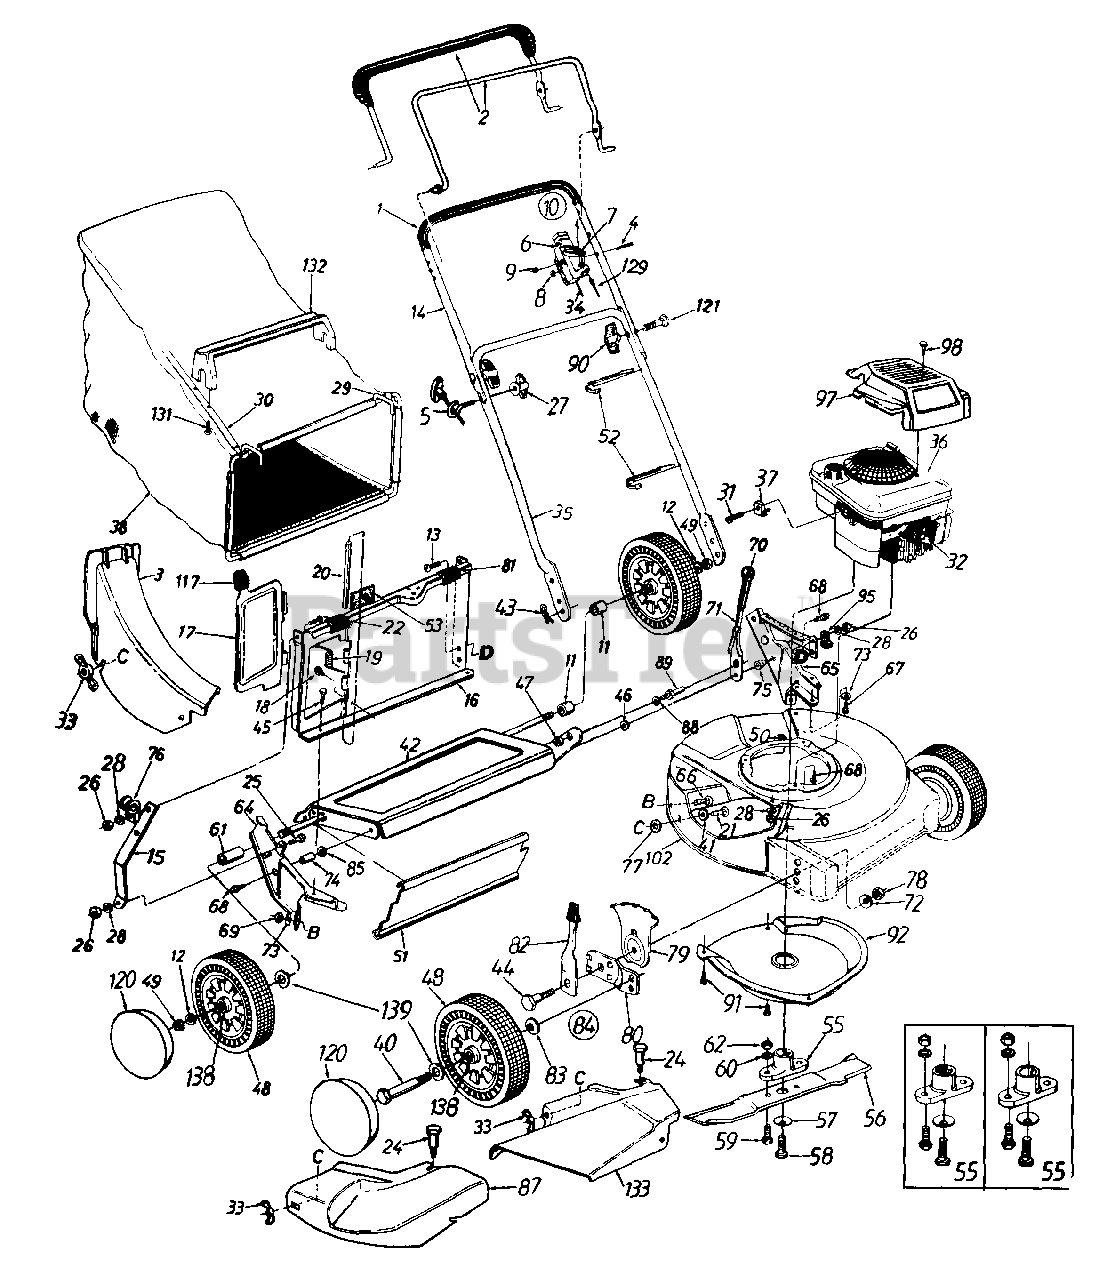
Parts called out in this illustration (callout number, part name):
1	Grip
3	Top Discharge Chute Ass'y.
4	Oval C-Sunk Ser.
5	Rope Guide
6	Throttle Body
7	Throttle Lever
8	Spr. Wash .66" I.D.
9	Hex L-Nut 1/4-20 Thd.
10	Throttle Box Comp.
11	Spacer .526" I D. x .690" O.D. x .640" Lg.
12	Fl-Wash .510" I.D. x .75"
13	Truss Mach. Scr. 1/4-20 x .62"
14	Upper Handle
19	Torsion Spring
20	Pivot Pin
21	Carriage Bolt 1/4-20 x .62"
22	Truss Mach. Scr. 1/4-20 x .75"
24	Shoulder Bolt .312" Dia. x .18" Lg. Special
25	Hex Bolt 1/4-20 x .62" Lg.
26	Hex Nut 1/4-20 Thd.
27	Handle Knob 1/4-20 Thd.
28	L-Wash. 1/4" I.D.
31	Hex Self-Tap Scr. #10-32 x .62"
32	Spark Plug Insulator
33	Wing Nut w/Washer
34	Throttle Control Wire 61"
36	Engine
37	Cable Clamp
38	21" Top Discharge Grass Bag
40	Shld. Bolt .498" Dia. x 1.45"
41	Fl-Wash .344" I.D. x .62"
44	Shld. Bolt .5" Dia. x .357"
45	Hex AB-Tap Scr. 1/4 x .62"
46	Fl-Wash .38" I.D. x 1.0"
47	Hex Jam Nut 3/8-24 Thd.
48	Wheel Ass'y. Comp. (w/o Ball Bearings)
49	Hex L-Nut 1/2-20 Thd.
51	Rear Flap 3.75" x 17.30" Lg.
52	Cable Tie
53	Foam Strip 1" Lg.
55	Blade Adapter Kit (Keyed)
56	21" Blade
57	Bell-Wash .39" I.D.
58	Hex Bolt 3/8-24 x 1.5" Lg.
59	Hex Bolt 3/8-24 x 1" Lg.
60	L-Wash. 3/8" I.D.
61	Sleeve .526" I.D. x .69"
62	Hex Nut 3/8-24 Thd.
64	R.H. Handle Wheel Brkt. Ass'y.
65	L.H. Handle Wheel Brkt. Ass'y.
66	Carriage Bolt 5/16-18 x .62"
67	Hex Wash. Hd. B-Tap Scr. 5/16-18
68	Hex Wash. Hd. TT-Tap Scr. 3/8-16
69	Hex Nut 5/16-18 Thd.
71	Height Adj. Lever
72	Bell-Wash .39" I.D. x 1.38" O.D.
73	Bell-Wash. 5/16" I.D.
74	Spacer .383" I.D. x .503" 0 D.
75	Shld. Spacer .500" Dia.
76	Rope Guide
77	Bolt Retainer 1/4 x .50" O.D.
78	Hex Nut 3/8-16 Thd.
79	Height Adj. Plate
81	Panel Clip
82	Spring Lever Ass'y. w/ Knob
83	Bell-Wash .38" I.D. x .88" 0.0.
84	Height Adj. Ass'y. Comp.- R.H.
85	Fl-Wash. 3/8" I.D. x 1" O.D.
87	Mulching Plug
88	L-Wash. 3/8" I.D.
89	Shld. Pin 3/8-24 x 1.43" Lg.
90	Hand Knob
91	Hex Wash. Hd. Tap Scr. 1/4 x .38" Lg.
97	XTE Engine Shroud (Black)
98	Screw #10 x 1.25" Lg.
120	Hub Cap
121	Curved Hd. Bolt 5/16-18 x 2" Lg.
129	Control Cable - 44" Lg.
131	Hex AB-Tap Scr. #12 x 1.0"
132	Bag Handle
133	Side Chute Deflector Ass'y.
138	Ball Bearings 2 Req'd. Per Wheel
139	Wave Washer
